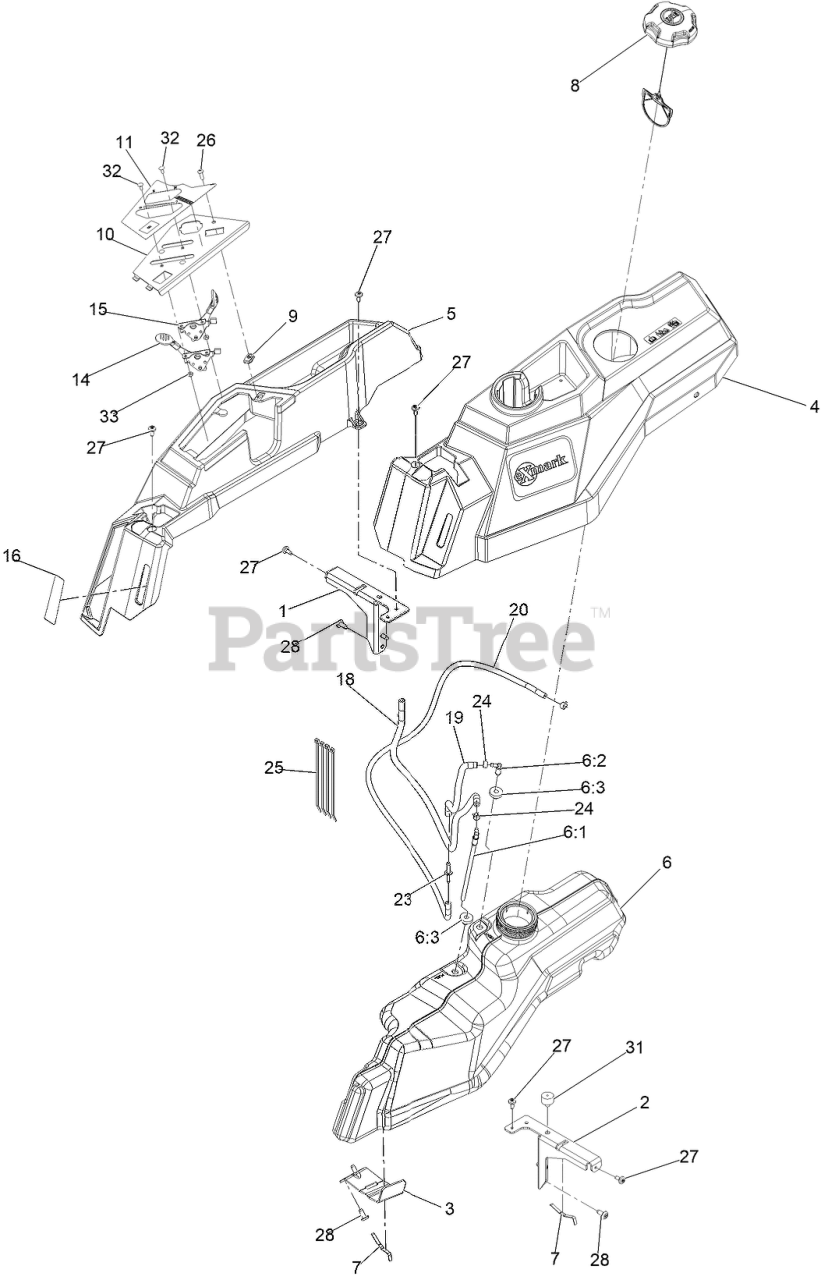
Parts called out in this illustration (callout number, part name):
1	SUPPORT-POD, RH
2	SUPPORT-POD, LH
3	SUPPORT-TANK, FUEL
4	POD- LH
5	POD- RH
6	FUEL TANK ASM
6:1	Connector-Elbow, 90 DEG
6:2	FITTING-PLASTIC
6:3	BUSHING
7	SPRING
8	CAP-FUEL, RATCHETING
10	PANEL- CONTROL
11	DECAL-CONTROL PANEL
14	ASM,THROTTLE CABLE
15	CABLE-CONTROL, CHOKE
16	DECAL- COVER SC
18	HOSE-FUEL
19	HOSE-FUEL
20	Hose-Fuel
23	ADAPTOR-ORIFICE
24	CLAMP-HOSE
25	TIE-CABLE
26	SCREW-PRH
27	SCREW-SHOULDER
31	BUMPER-GROMMET
32	BOLT-CARR
33	NUT-LOCK, NI
